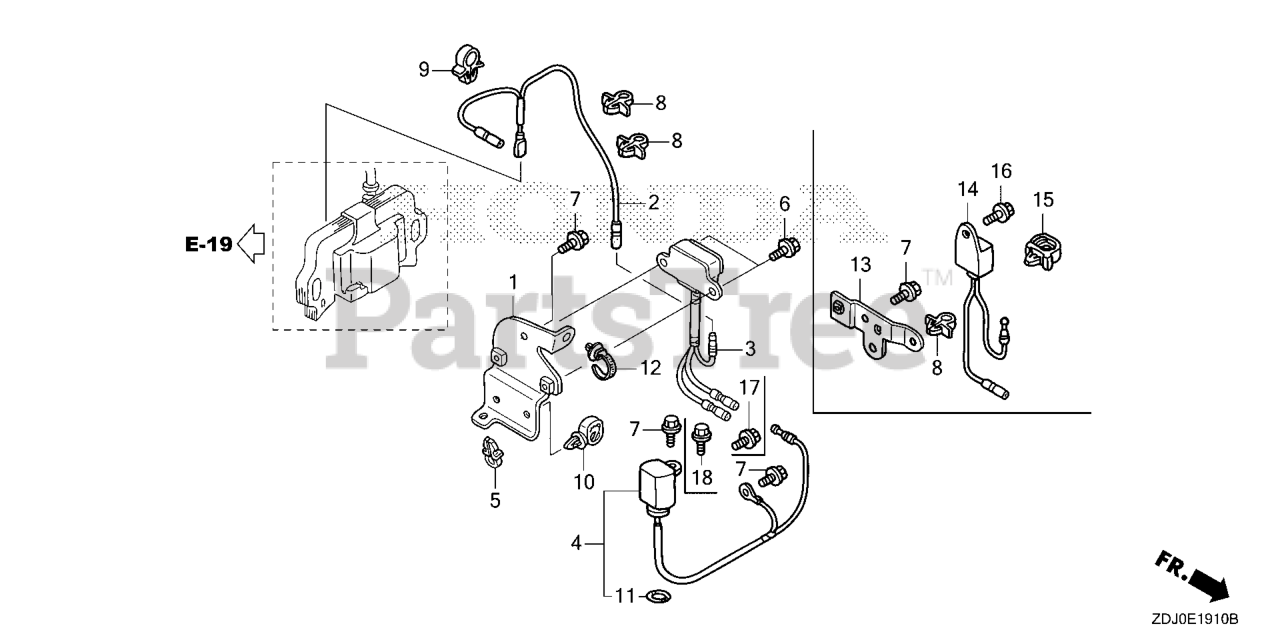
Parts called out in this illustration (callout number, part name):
1	BRACKET, OIL ALERT UNIT
2	WIRE, STOP SWITCH
3	ALERT UNIT, OIL (START LED)
4	SWITCH ASSY., OIL LEVEL
5	HOLDER, STOP SWITCH WIRE Use up to Engine SN 2056819.
6	BOLT, FLANGE (5X8)
7	BOLT, FLANGE (6X14)
8	CLIP, CABLE (A)
9	CLIP B, CABLE
10	CLIP, WIRE HARNESS (25MM)
11	O-RING (11.8X2.4)
12	CLIP, HARNESS BAND (151.5MM) (NATURAL)
17	BOLT, FLANGE (6X12) (CT200)
18	BOLT, FLANGE (6X14)
